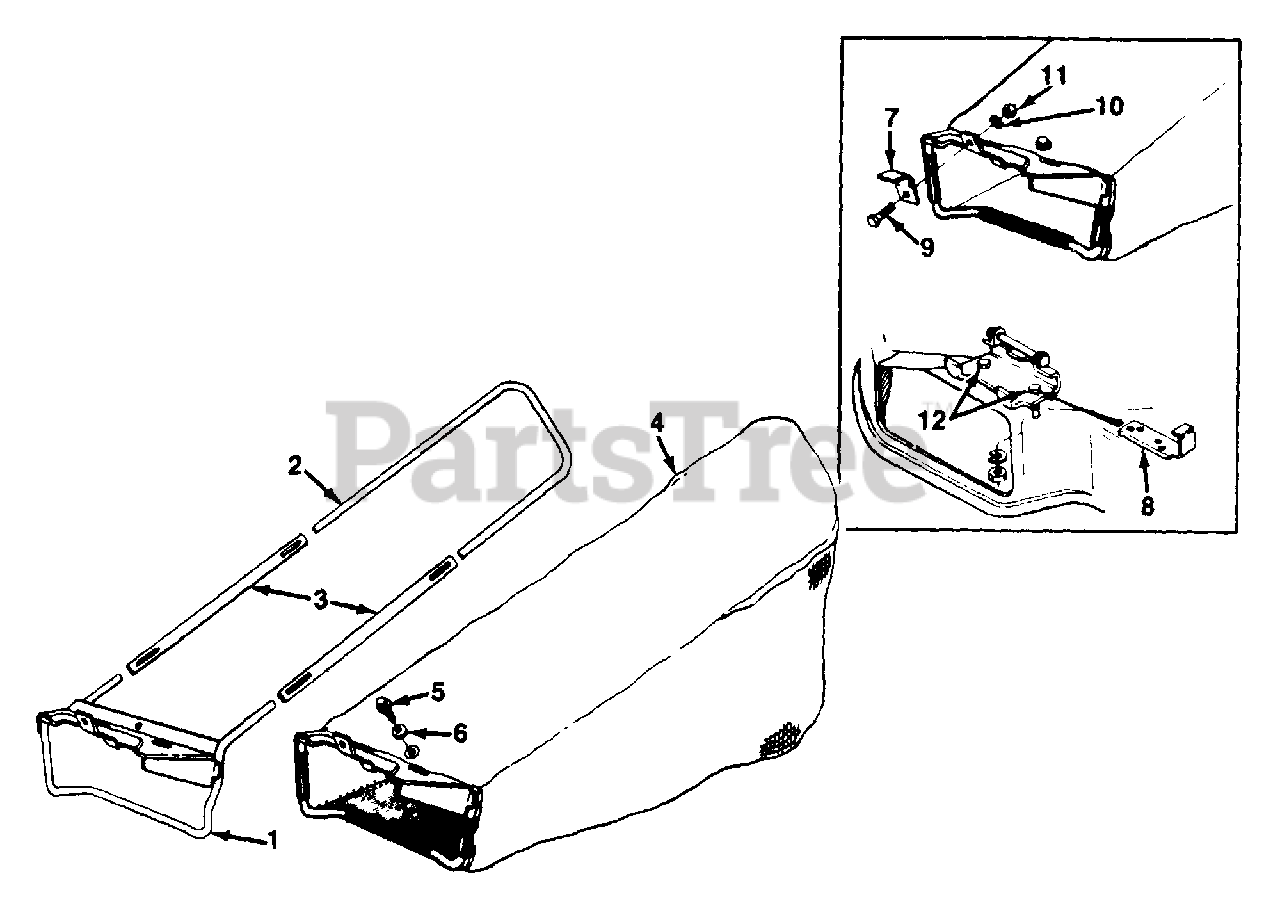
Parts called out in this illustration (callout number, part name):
4	Grass Bag
5	Hex Wash Hd. TT-Tap Scr. 1/4-20 x 5" Lg.
6	Bell-Wash. 1/4" I.D.
7	Deflector Stop
8	Support Plate
9	Hex Bolt 1/4-20 x .5" Lg.
10	L-Wash. 1/4" I.D.
11	Hex Nut 1/4-20 Thd.
12	Hex Bolt 1/4-20 x .62" Lg.
